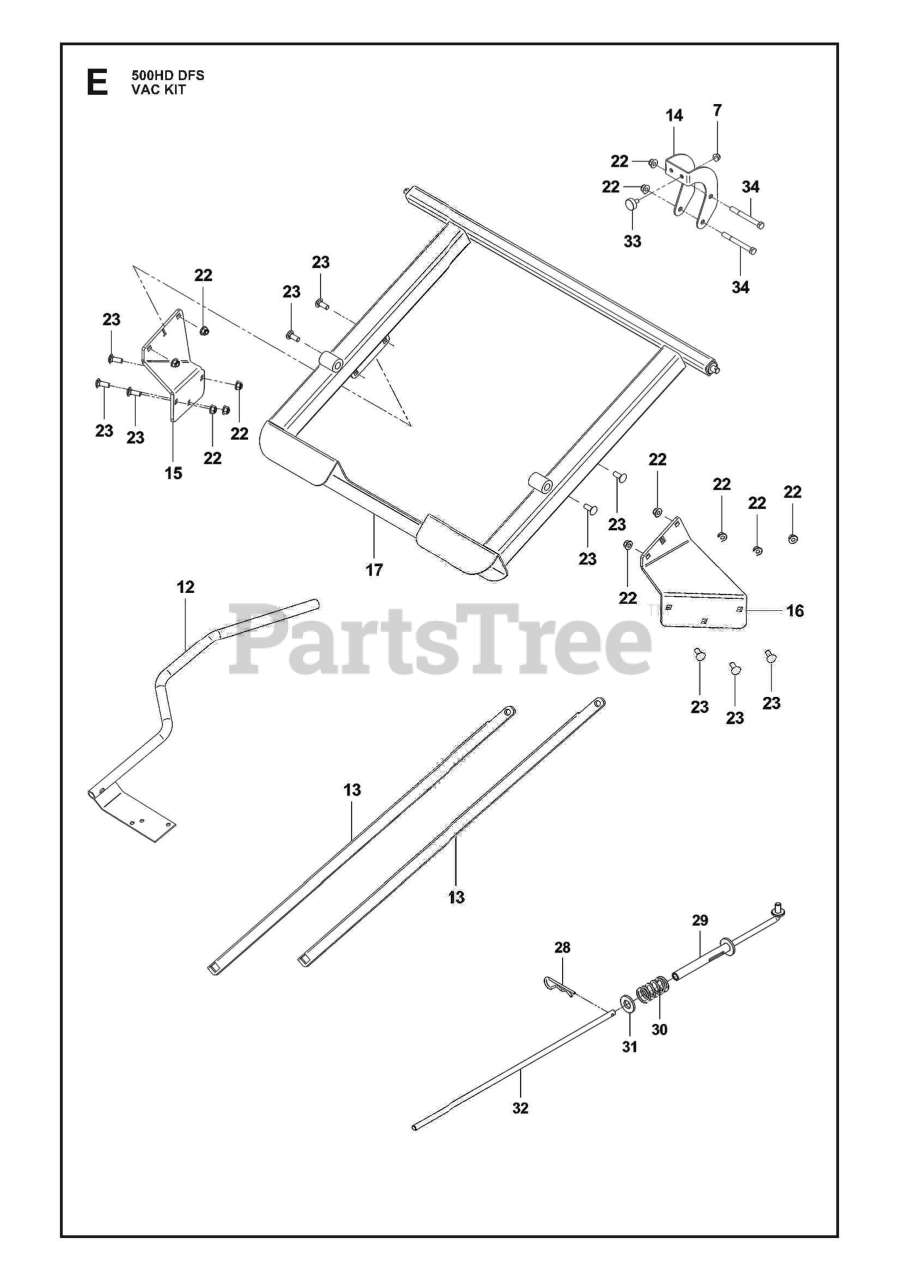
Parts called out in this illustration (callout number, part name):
7	NUT HEXAGON FLANGE 5/16-18 ST
12	HANDLES
13	LINKS
14	BRACKETS
15	FRAMES
16	FRAMES
17	FRAMES
22	GSPW Nuts
23	Bolts
28	Pins
29	RODS
30	SPRINGS
31	Washers
32	LATCH
33	ANTIVIBTAION ELE
34	HCS 3/8-16 X 3-1/2 GR5 ZD
